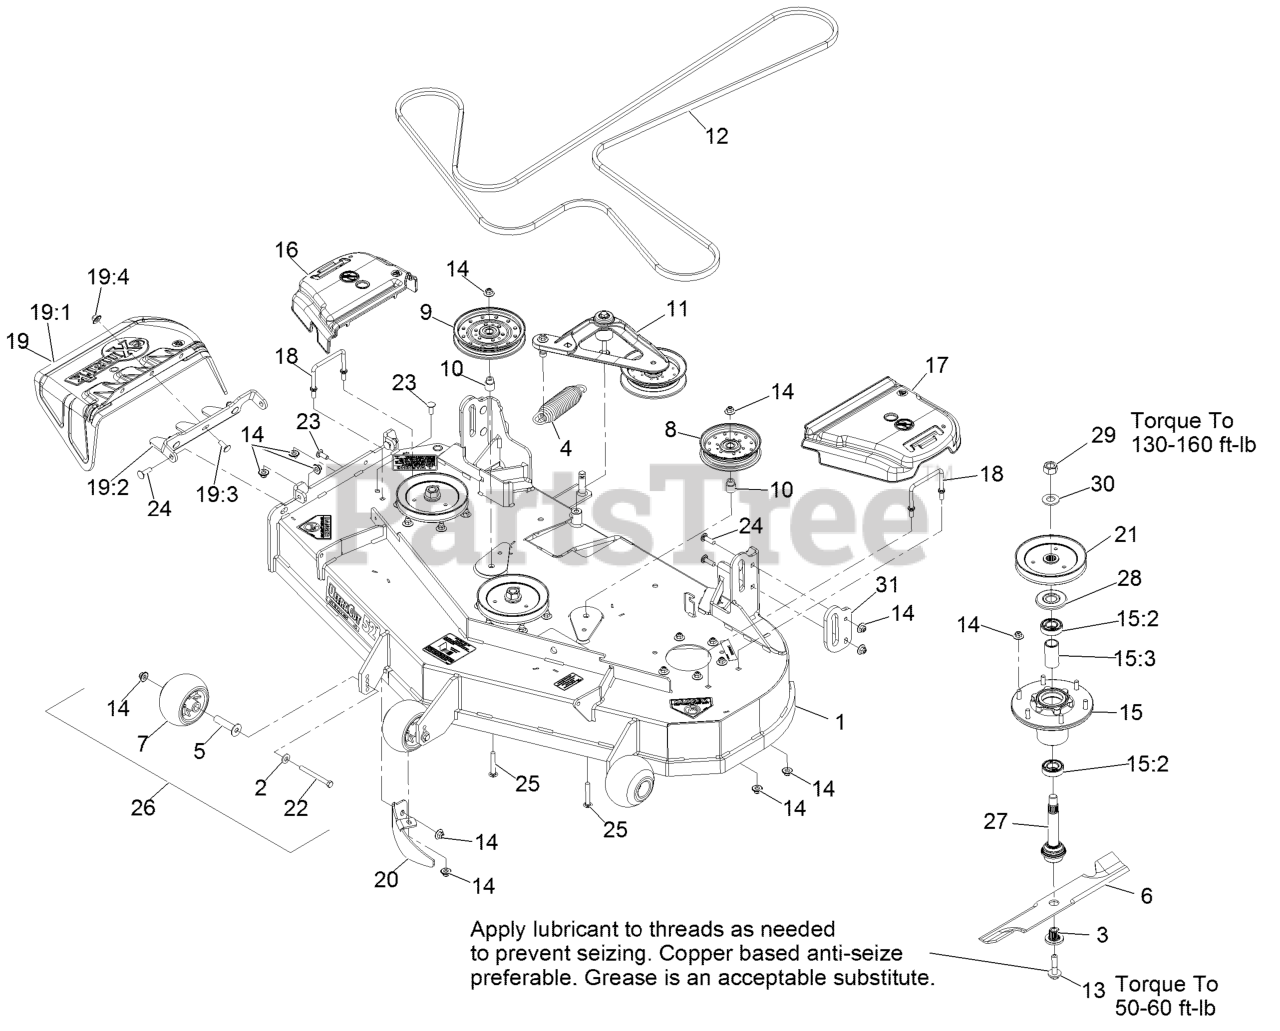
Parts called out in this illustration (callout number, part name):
1	ASM, DECK W/DECALS 524
2	WASHER-BELLEVILLE
3	BUSHING,SPLINED
4	SPRING-EXTENSION
5	AXLE, ROLLER
7	ROLLER-SCALP, ANTI
10	BUSHING-IDLER
11	DECK IDLER ASM
12	BELT,V-B X 186.00"
13	SCREW,SEMS 1/2-20 X 2.19
14	Nut-Nyloc 3/8-16 Flg
15	ASM-CUTTER HSG WITH BEARINGS
15:2	BEARING-BALL
15:3	SPACER-BEARING
16	COVER-BELT, RH
17	COVER-BELT, LH
18	WIREFORM-COVER
19	ASM,DISCHARGE CHUTE
19:1	CHUTE,DISCHARGE
19:2	BRACKET,DISCHARGE CHUTE
19:3	SCREW-CARR
19:4	Nut-Nyloc 3/8-16 Flg
20	BAFFLE-DOGLEG, LZE-PNS-52
21	SHEAVE,BLADE DRIVE 6.50
22	SCREW-HH 3/8-16 X 3 3/4 GR 8
23	SCREW-CARR
24	Bolt-Carriage 3/8-16 X 1 1/4
25	SCREW-CARR
26	KIT, ANTI-SCALP ROLLER
27	ASM-SPINDLE AND SEAL
28	GUARD,BEARING TOP .989
29	NUT-HEX
31	PLATE-REINF, PUSH TOWER
